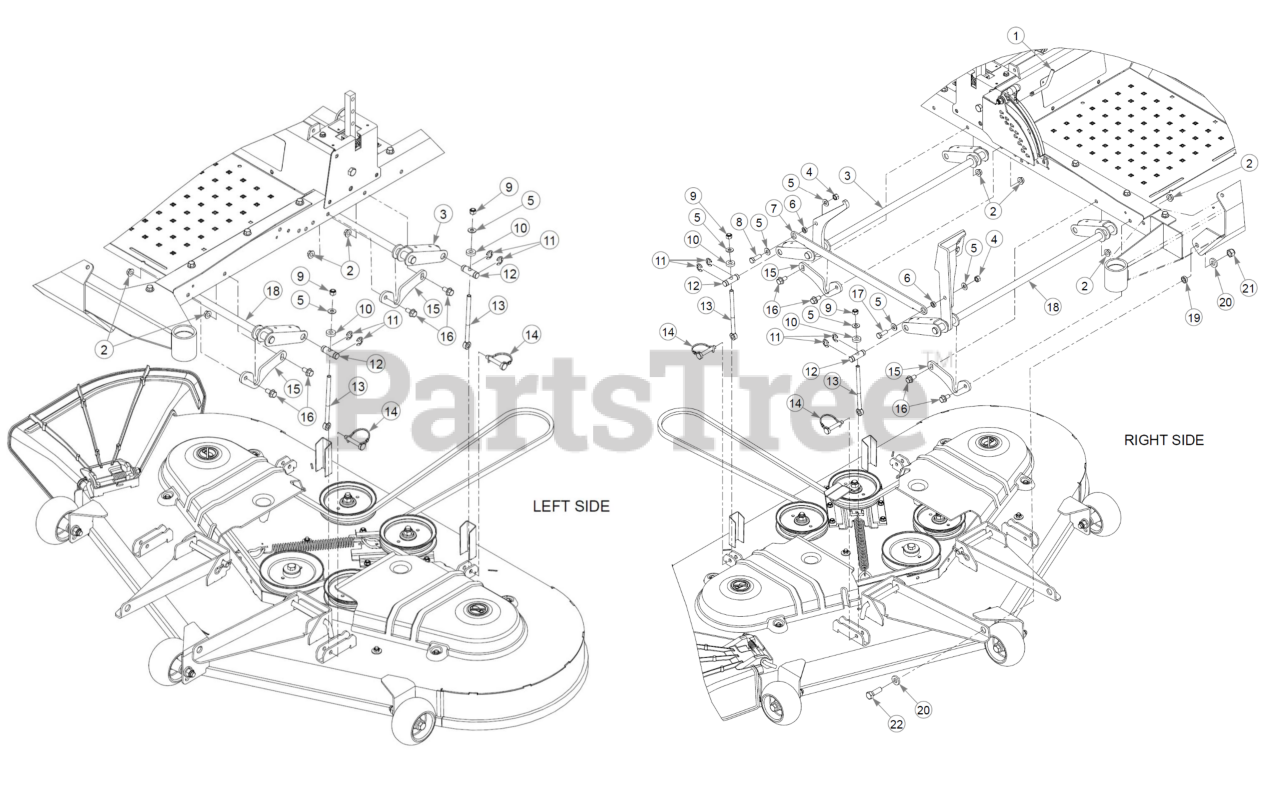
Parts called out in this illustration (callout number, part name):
1	PIN, INDICATOR
2	NT .375-16 FLKG5
3	DECK LIFT W/A, REAR
4	NT .375-16HXG5
5	FW 0.379X.82X.06 HD ZN
6	PIVOT SPACER BUSHING
7	LIFT PEDAL, LINK
8	CS .375-16X1.12 HX G5 Z
9	ASSEMBLY BLADE
10	FW .41X.94X.25 UHMW
11	CLIP E,.625x.480x.042 Z
12	PIVOT, DECK LIFT
13	LINK, DECK LIFT
14	CE .375 x 2.00 W/BALE
15	PIVOT BLOCK, DECK LIFT
16	CS .375-16X0.75 HXF G5ZN
17	CS .375-16X1.00 HX G5 ZN
18	DECK LIFT W/A, FRONT
19	PIVOT SPACER BUSHING
20	FW .531 x 1.063 x .175
21	NT .500-13NLG5
22	CS .500-13X1.50 HX G5 ZN
